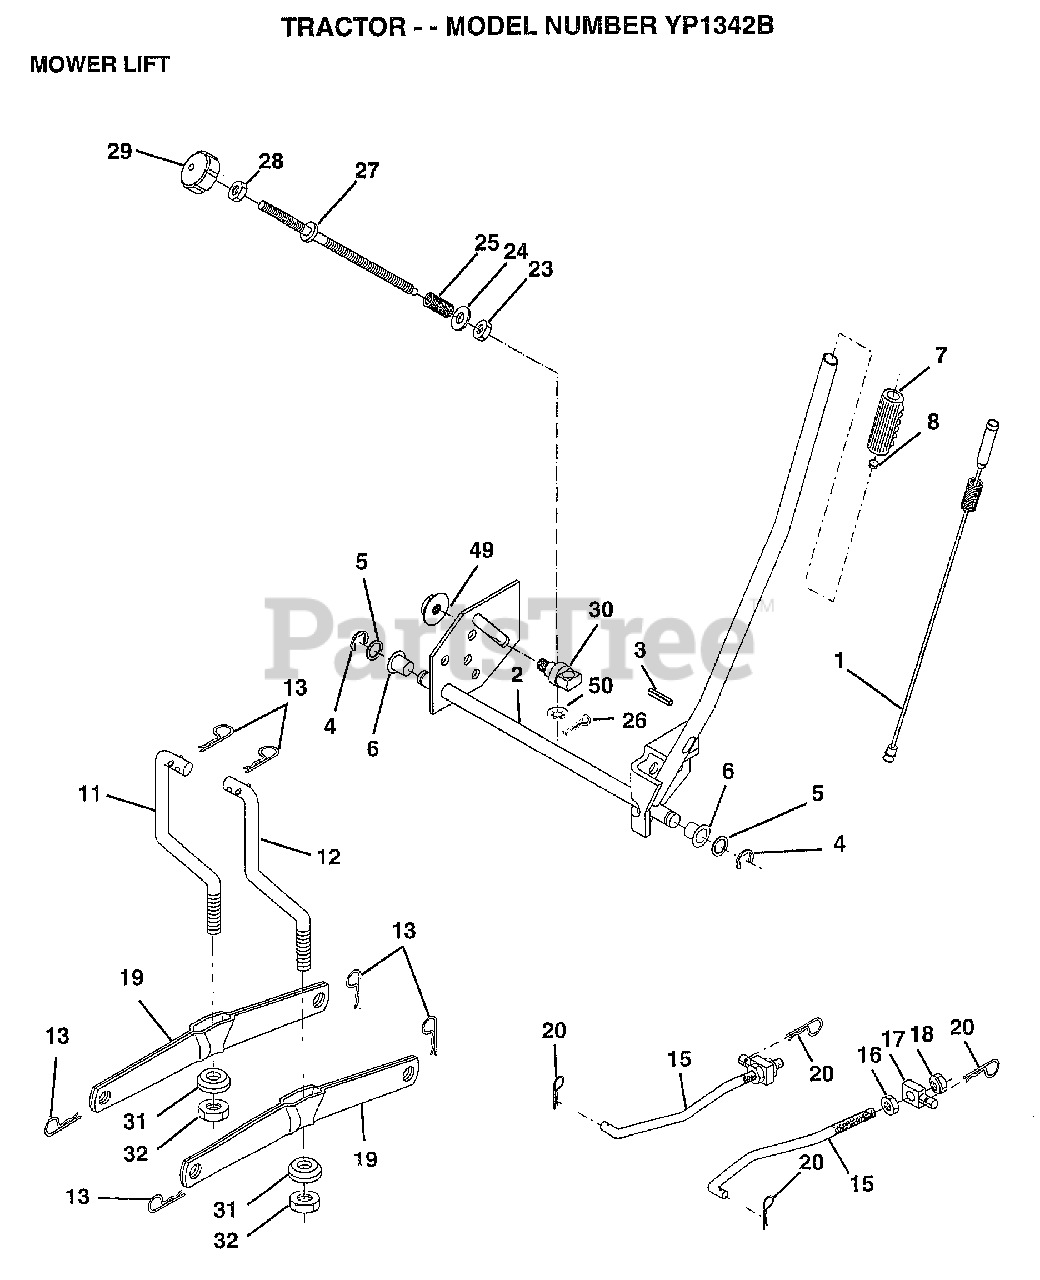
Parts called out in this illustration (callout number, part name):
1	WIRE ASM W.SPRING
2	"SHAFT ASM LIFT,RH"
3	PIN-GROOVE LT
5	WASHER
6	NYLON BEARING
7	GRIP HANDLE
15	LINK.FRONT
16	NUT
17	TRUNION
18	NUT.LK.W/WSH.1/2.
19	ARM SUSP REAR
20	RETAINER.SPRING
23	NUT T
24	WASHER
25	SPRING T
28	NUT
29	KNOB INF 3/8-16
30	TRUNNION
31	BEARING PVT LH
32	NUT.CROWNLOCK.3/8
49	NUT.HXFLG.LOCK.
50	NUT PUSH M
